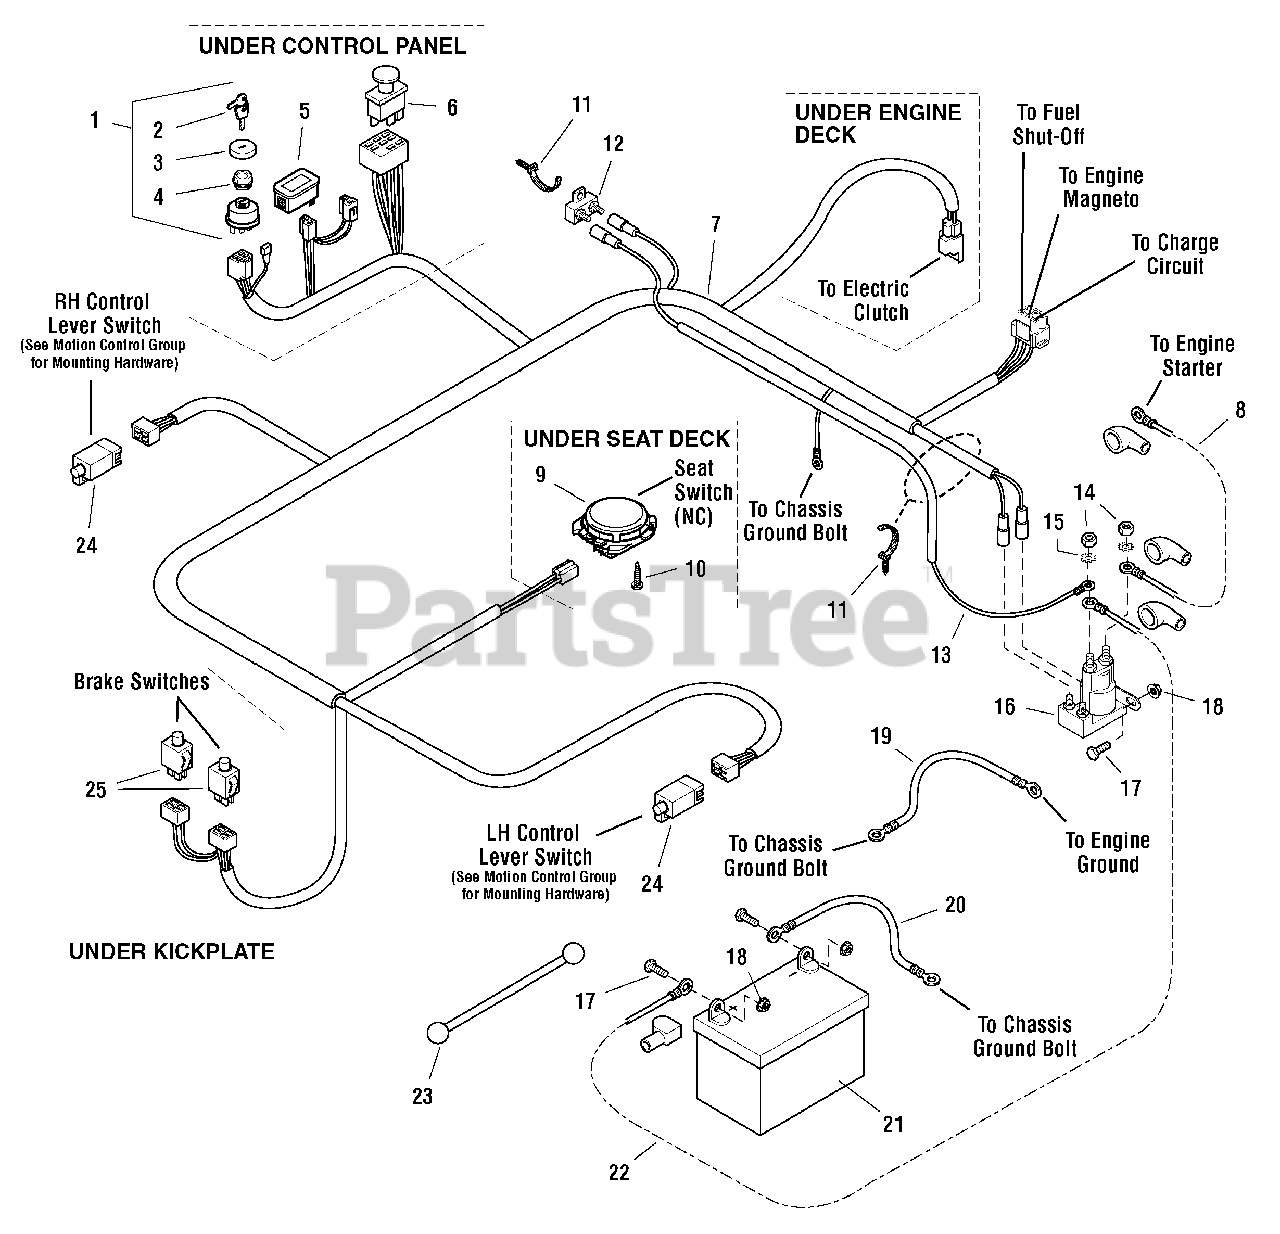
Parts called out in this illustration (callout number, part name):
1	SWITCH, Ignition, (Includes Ref 2-4)
2	KEY, Ignition Molded (Set of 2)
4	NUT, Plastic
5	HOUR METER, Digital (Includes Retaining Ring)
6	SWITCH, PTO
7	HARNESS ASSEMBLY, Main
8	CABLE, #6 X 15" LONG, Ring Terminal
9	SWITCH, Seat, Gray, NC
10	CAPSCREW, Hex Washer Head PLASTITE, 1/4 X 1/2
11	CABLE TIE, Push Mount
12	CIRCUIT BREAKER, 20A
13	WIRE ASSEMBLY, Ciruit Breaker
14	NUT, Hex Jam 5/16-24
15	WASHER, Light Lock, 5/16
16	SOLENOID
17	CAPSCREW, Hex Head, 1/4-20 X 3/4
18	NUT, Hex Serrated Flange, 1/4-20
19	CABLE, #6 X 10" LONG, Ring Terminal
20	CABLE, #6 X 22" LONG, Ring Terminal
21	BATTERY, 12 Volt
22	CABLE, #6 X 30" LONG, Ring Terminal
23	STRAP, BATTERY, 14 LONG, Rubber
24	SWITCH, PLUNGER, N.O./N.C.
25	SWITCH, DP NO/NC SNAP-IN
